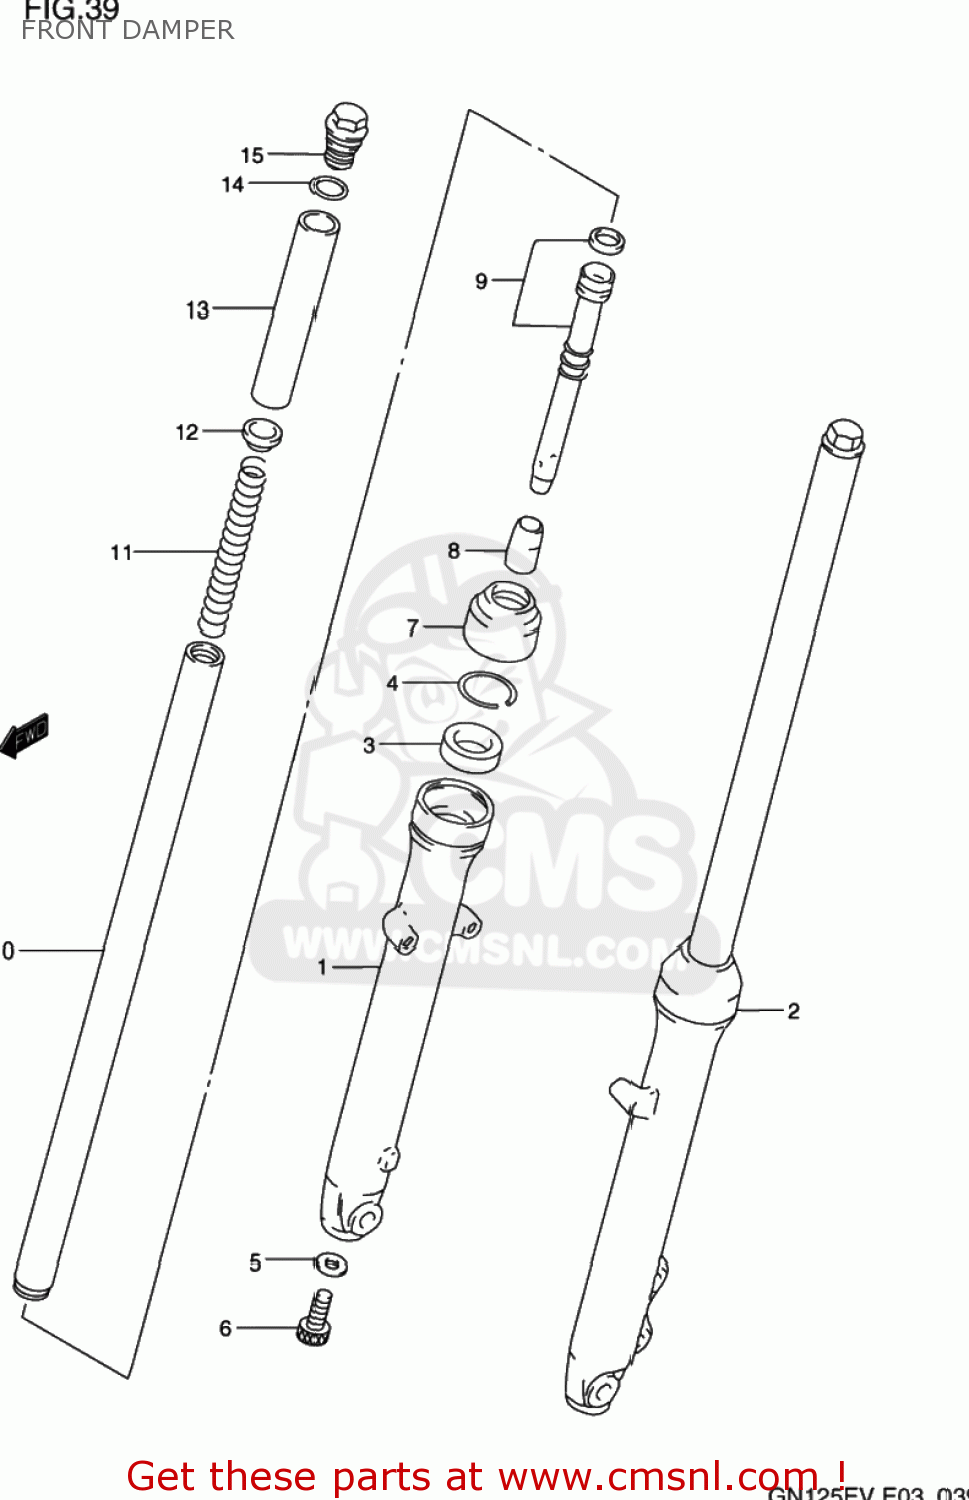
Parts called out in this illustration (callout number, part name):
1	TUBE,OUTER,R
2	TUBE,OUTER,L
3	SEAL,OIL
4	RING,SNAP
5	GASKET (NAS)
6	BOLT,FORK CYLINDER(10X25)
7	SEAL,DUST
8	PIECE,OIL LOCK
9	CYLINDER
10	TUBE,INNER
11	SPRING
12	GUIDE,SPRING COVER
13	SPACER
14	O RING
15	CAP
